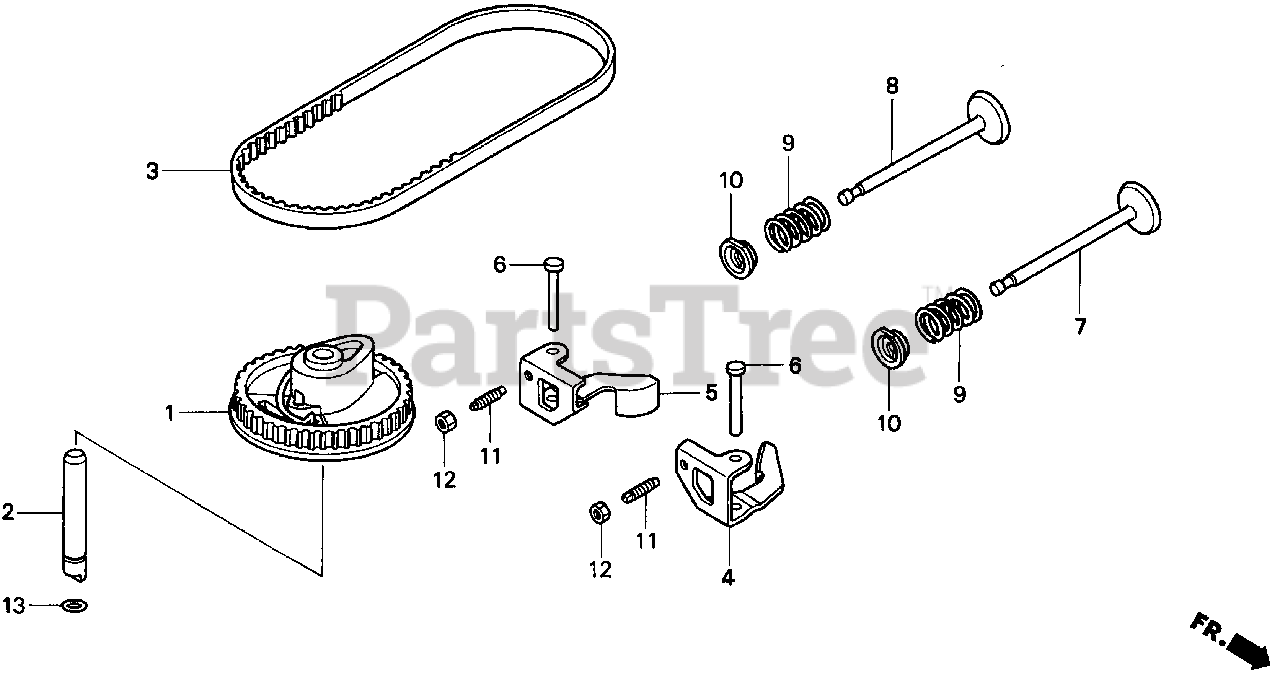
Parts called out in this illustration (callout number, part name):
1	PULLEY, CAMSHAFT
2	SHAFT, CAM PULLEY
3	BELT, TIMING (84HU7 G-200)
4	ARM, IN. VALVE ROCKER
5	ARM, EX. VALVE ROCKER
6	SHAFT, ROCKER ARM
7	VALVE, IN.
8	VALVE, EX.
9	SPRING, VALVE
10	RETAINER, IN. VALVE SPRING
11	SCREW, TAPPET ADJ.
12	NUT, TAPPET ADJ.
13	O-RING (6.8X1.9)
